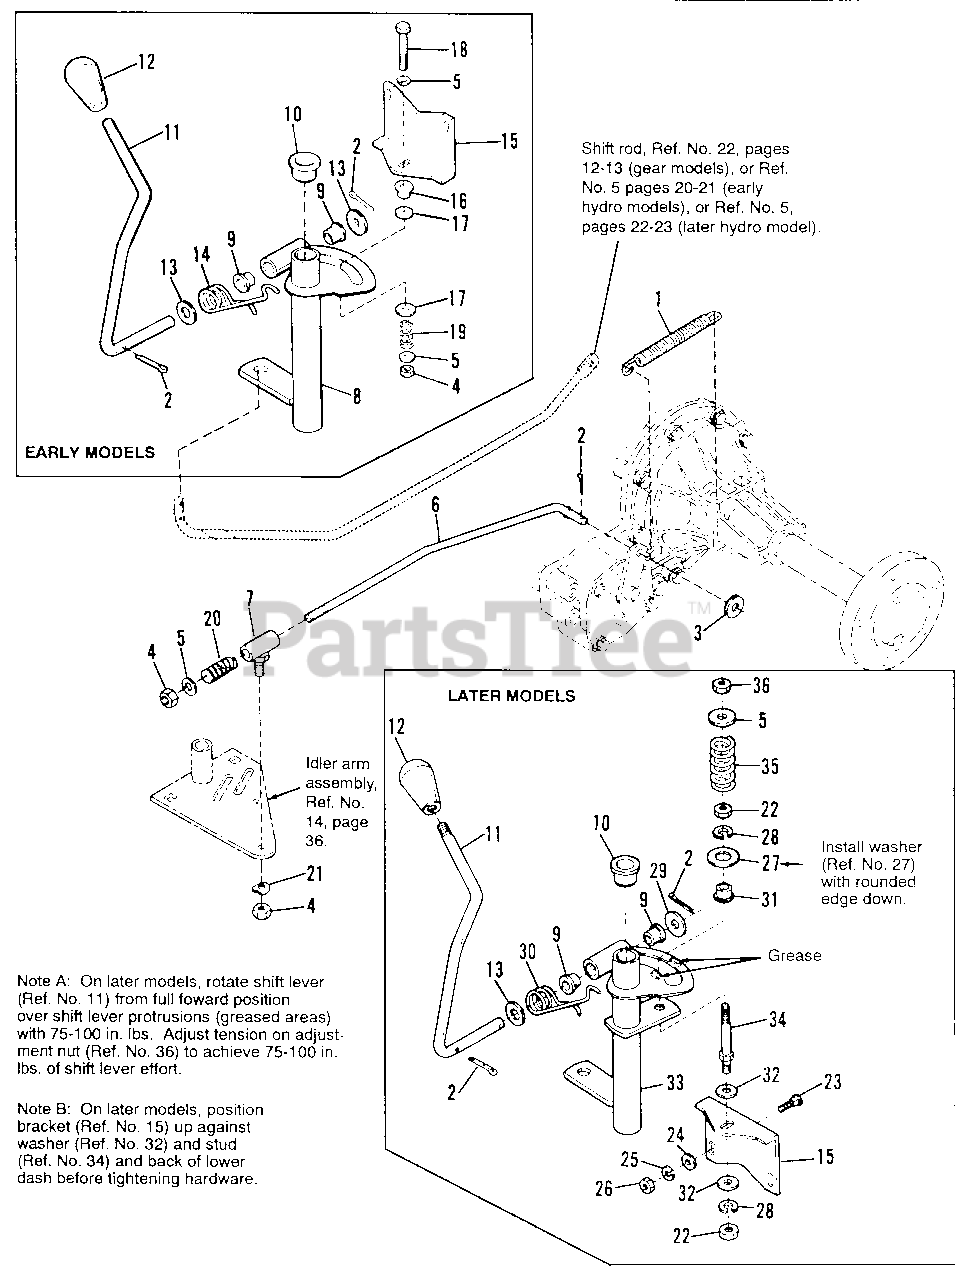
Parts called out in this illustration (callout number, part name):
1	SPRING, Extension
2	COTTER PIN
3	WASHER, Plain
4	NUT, Hex, Lock, ESNA, 5/16-18
5	WASHER, Flat (Qty. 2 on later models)
7	ROD GUIDE ASSY.
8	SHIFT LEVER ASSY. (Early models only)
9	BUSHING, Plastic, 1/2 Dia.
10	BUSHING, Plastic, 3/4 Dia.
11	LEVER, Shift
12	KNOB, Plastic (Mfg. Nos. 1692006, 1692036, 1692042, 1692044)
12	KNOB, Soft (Mfg. Nos. 1692440, 1692442, 1692446, 1692448, 1692502)
13	WASHER, Plain (Qty. 1 on later models)
14	SPRING, Torsion (Early models)
15	BRACKET, Tension (See Note B on illustration page)
16	SPACER (Early models only)
17	WASHER, Plain, 5/8, 21/32 (Early models only)
18	CAPSCREW, Hex, 5/16-18 x 1-3/4 (Early models only)
19	SPRING (Early models only)
20	SPRING, Compression
21	WASHER, Curved Spring
22	NUT, Hex, 5/16-18 (Later models only)
23	SCREW, Rd. Hd. Sq. Nk., 1/4-20 x 3/4
24	WASHER, Plain, 1/4
25	LOCKWASHER, 1/4
26	NUT, Hex, 1/4-20
27	WASHER, H.T.
28	LOCKWASHER, 5/16
30	SPRING, Torsion
32	WASHER, Plain, 5/16
33	SHIFT LEVER ASSY. (Later models only)
35	SPRING, Compression
36	NUT, Hex, Nylon Lock, 5/16-18 (See Note A on illustration page)
